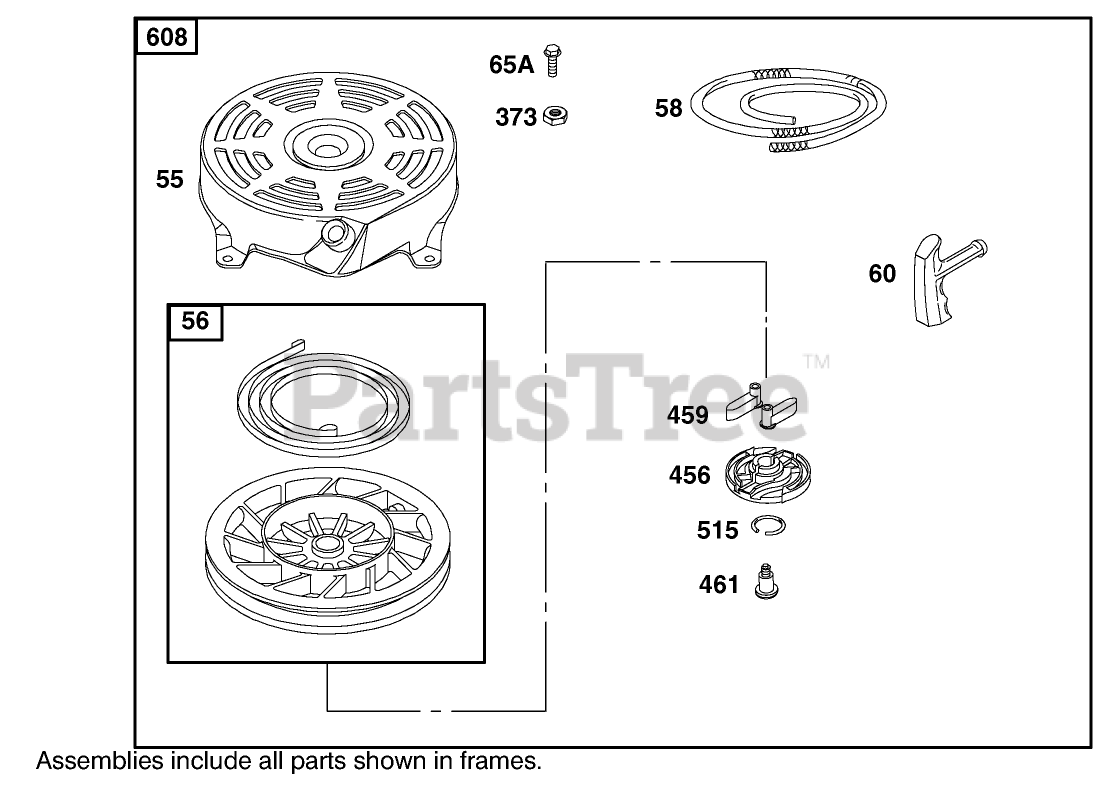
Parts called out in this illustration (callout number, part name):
56	PULLEY-STARTER, REWIND
58	ROPE-STARTER
65A	SCREW-HH
373	NUT-HEX
456	RETAINER-STARTER, REWIND
459	PAWL-STARTER
515	SPRING-TORSION
608	REWIND ASM
